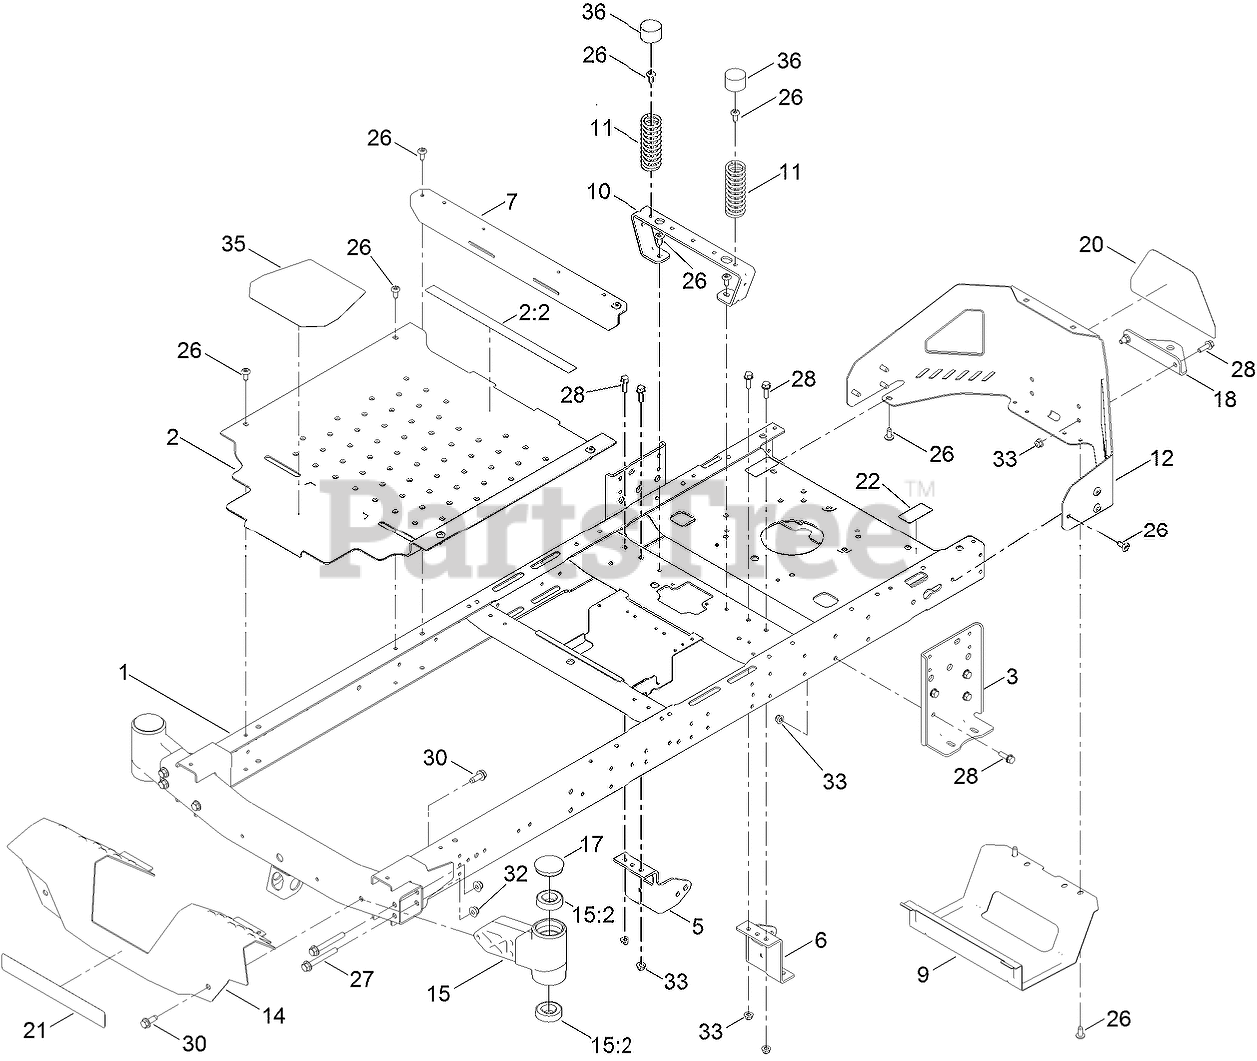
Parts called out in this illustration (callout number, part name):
1	FRAME ASSEMBLY
2	PAN-FLOOR ASM
2:2	DECAL-WARNING
3	PLATE-MOUNT, HYDRO
5	MOUNT-HYDRO, FRONT (RIGHT)
6	MOUNT-HYDRO, FRONT (LEFT)
7	BRACE-CROSS
9	GUARD-MUFFLER
10	SUPPORT-SEAT
11	SPRING-COMPRESSION
12	GUARD-ENGINE
14	FOOTREST
15	AXLE STUB ASM
15:2	BEARING-BALL
17	CAP-GREASE
18	BRACKET-HITCH
20	DECAL-TIMECUTTER
21	DECAL-TIMECUTTER
22	DECAL-BYPASS
27	SCREW-HHF
28	SCREW-HHF
30	SCREW-HWH
32	NUT-HF, NI
33	NUT-HF
35	TREAD-STEP
36	CAP-PROTECTOR
